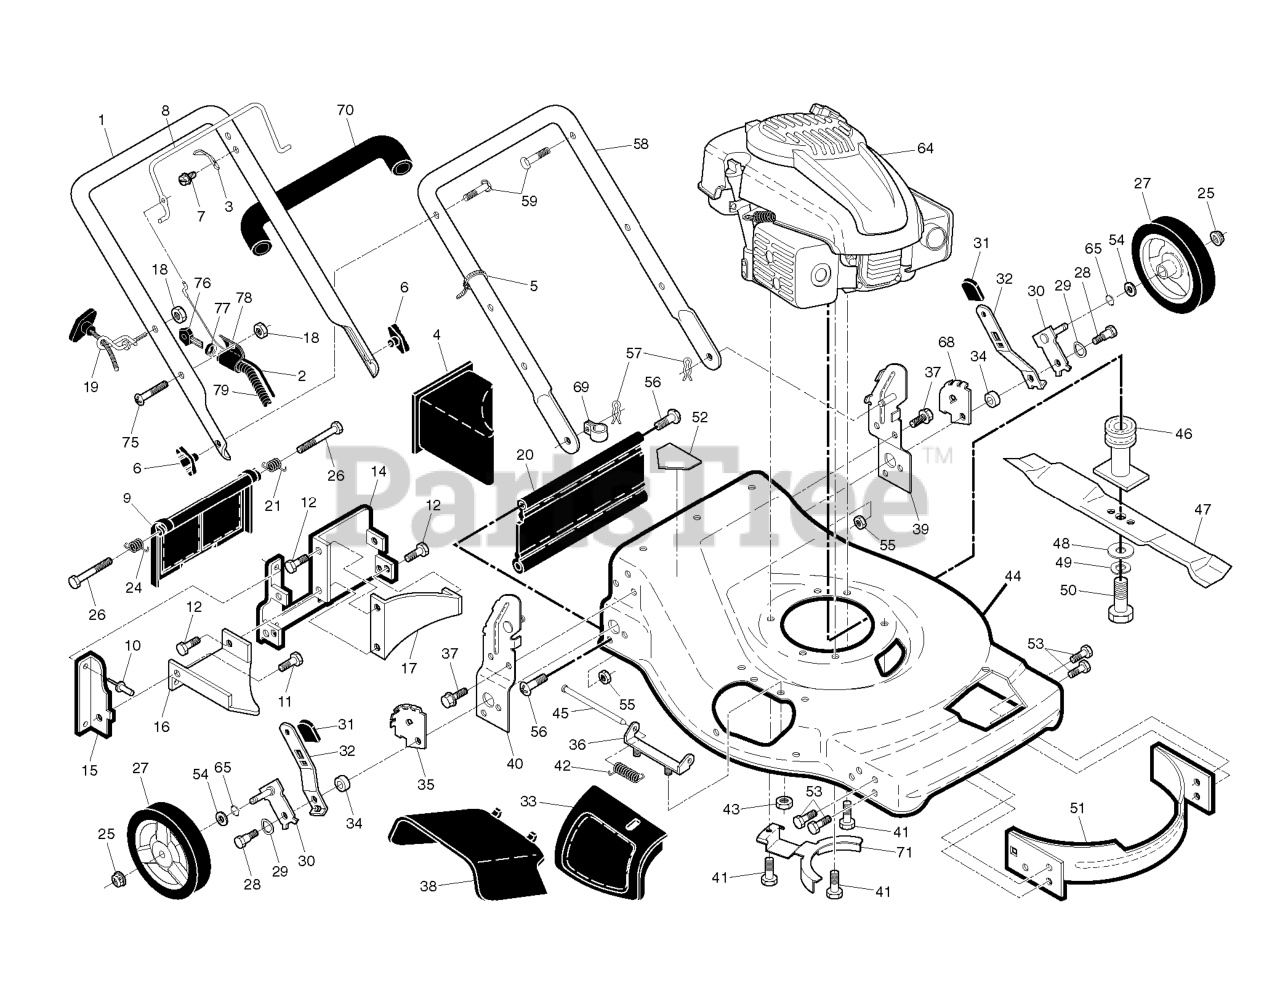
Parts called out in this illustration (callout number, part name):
1	HANDLE.ASM.UP.CREASED.GRE.W/GR
2	CABLE.MZR.W/KEY.START SW.51.62
3	BRACKET UPSTOP
4	PLUG.MULCH.22RD
5	TIE GUIDE
6	KNOB, DEFLECTOR
8	CONTROL BAR
9	REAR DOOR ASSY
10	RIVET BLIND
11	SCREW.HXTAP.10-24
12	SCREW 14-20 X 5/8
14	PLATE.BACK
15	SIDE BAFFLE
16	DISCHARGE BAFFLE
17	REAR BAFFLE
18	NUT
19	RB GUIDE.ROPE.STD.BLK.ZIN WSL
20	SKIRT.REAR.22RD/SD.FO/VE
21	SPRING.LH.22.REAR.DOOR.EZ.EMPT
24	SPRING.RH.22.REAR.DOOR.EZ.
25	NUT.HEX.FLANGE.3/8-16.LO(3 2)
27	WHEEL & TIRES ASSY, FRONT
28	BOLT SHOULDER 3/8 -16X1
29	WASHER.CURVED.CYLINDRICAL
30	AXLE ARM ASSY.
31	SELECTOR KNOB
32	SELECTOR SPRING, FRONT
33	DOOR.MULCH.22.REAR.FWGD.GREY
34	SPACER.HEIGHT.ADJUSTER
35	WHEEL ADJUSTING BRACKET
36	BRACKET.ASM.HINGE.21.FWGD.
37	BOLT.HEX.HD.WASHER.5/16-18X.75
38	DEFLECTOR.CLIPPING.22.GREY
39	BRACKET.ASM.HDL.LT.EZEM.22.ORA
40	BRACKET.ASM.HDL.RT.EZEM.22.ORN
41	BOLT 3/8-16X1-1/8
42	SPRING.TORSION
43	LOCKNUT.NYLOC.1/4-20
44	HOUSING.22.TORUS.FWD.ORANGE.WA
45	ROD.HINGE.21
46	RP ADAPTER.BLADE.25MM.21F
47	BLADE.22.MULCH.STANDARD
48	WASHER,HARDEN
49	LOCKWASHER
50	SCREW, HEX HD 3/8-24 X 1-3/8
51	FRONT BAFFLE KIT
52	DANGER DECAL
53	SCREW 1/4X20
54	WASHER.FLAT.1/2
55	LOCKNUT
56	HINGE SCREW
57	HAIRPIN COTTER
58	HANDLE.LOWER.PNT
59	BOLT, HANDLE 5/16-18X1.75
65	O-RING..070X.487.NEOPRENE
68	WHEEL ADJUSTING BRACKET LH
69	CLIP.CABLE.BLK
70	GRIP, FOAM
71	BRACKET.KEEPER.BELT
75	SCREW.(COMBINATION CONTROL)
76	KEY.MOLDED
77	NUT.CAP.SNAP-ON.KEY START
78	KIT.CONTROL.COMBI.KEYW/HARNESS
79	HARNESS.WIRING.CONTROL
